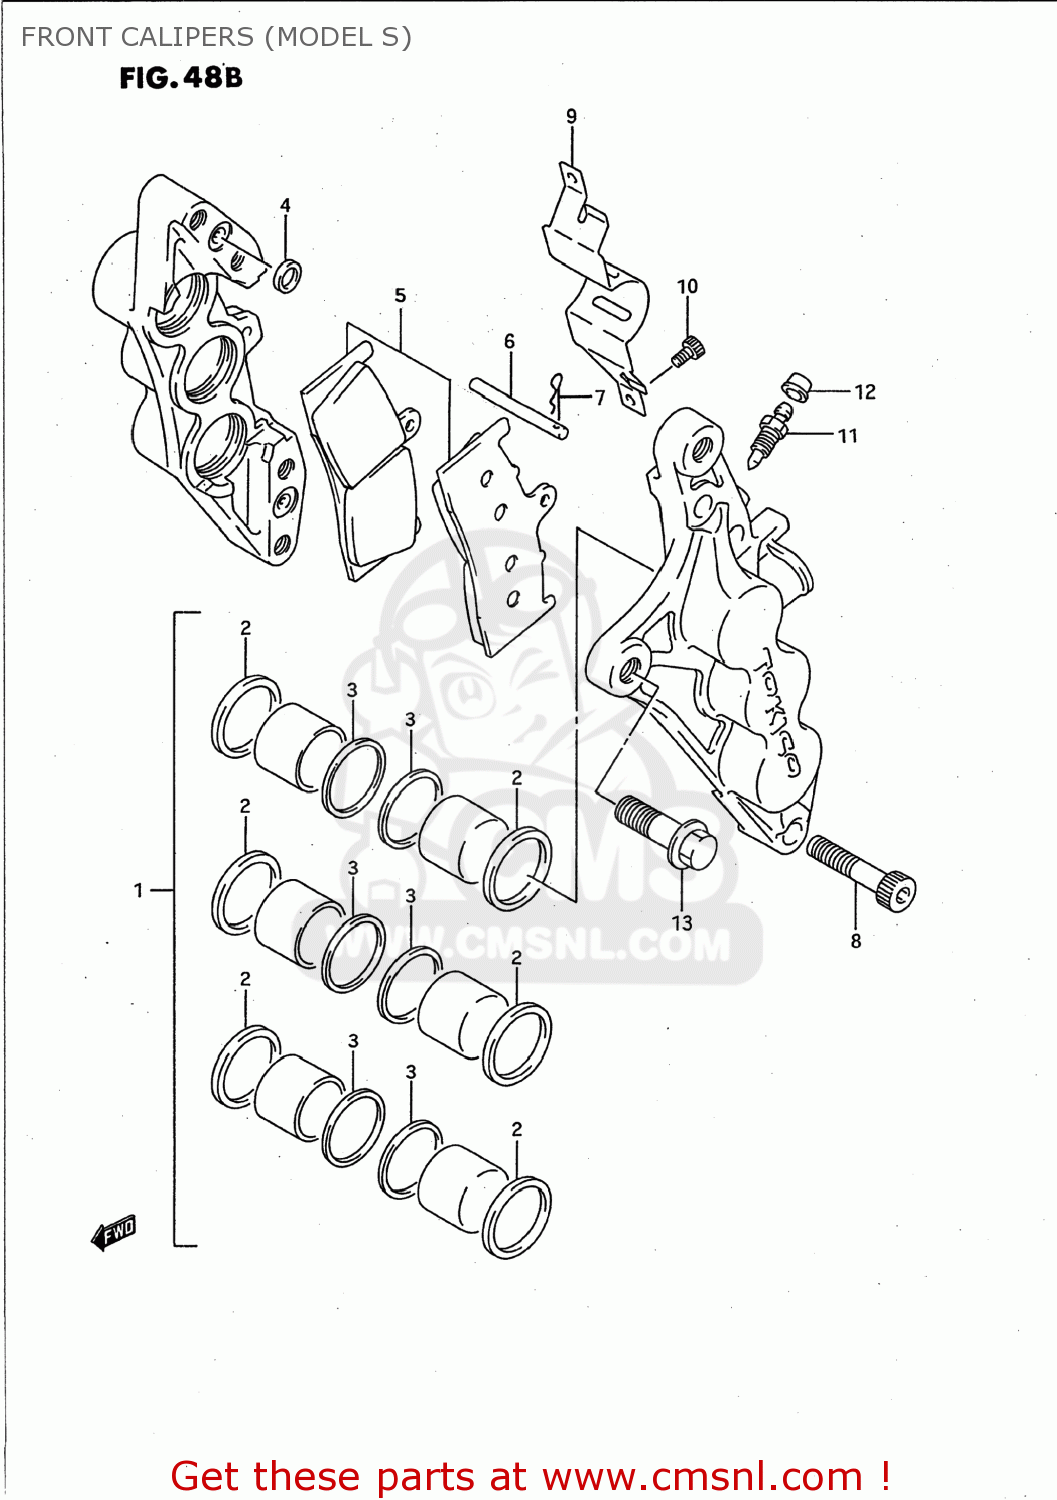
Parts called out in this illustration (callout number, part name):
1	PISTON SET
2	SEAL,PISTON
3	SEAL,WIPER
4	SEAL,JOINT
5	PAD SET (NAS)
6	PIN,PAD
7	CLIP,PAD PIN
8	BOLT,CALIPER
9	COVER,CALIPER
10	SCREW
11	BLEEDER
12	CAP,BLEEDER PLUG
13	BOLT
